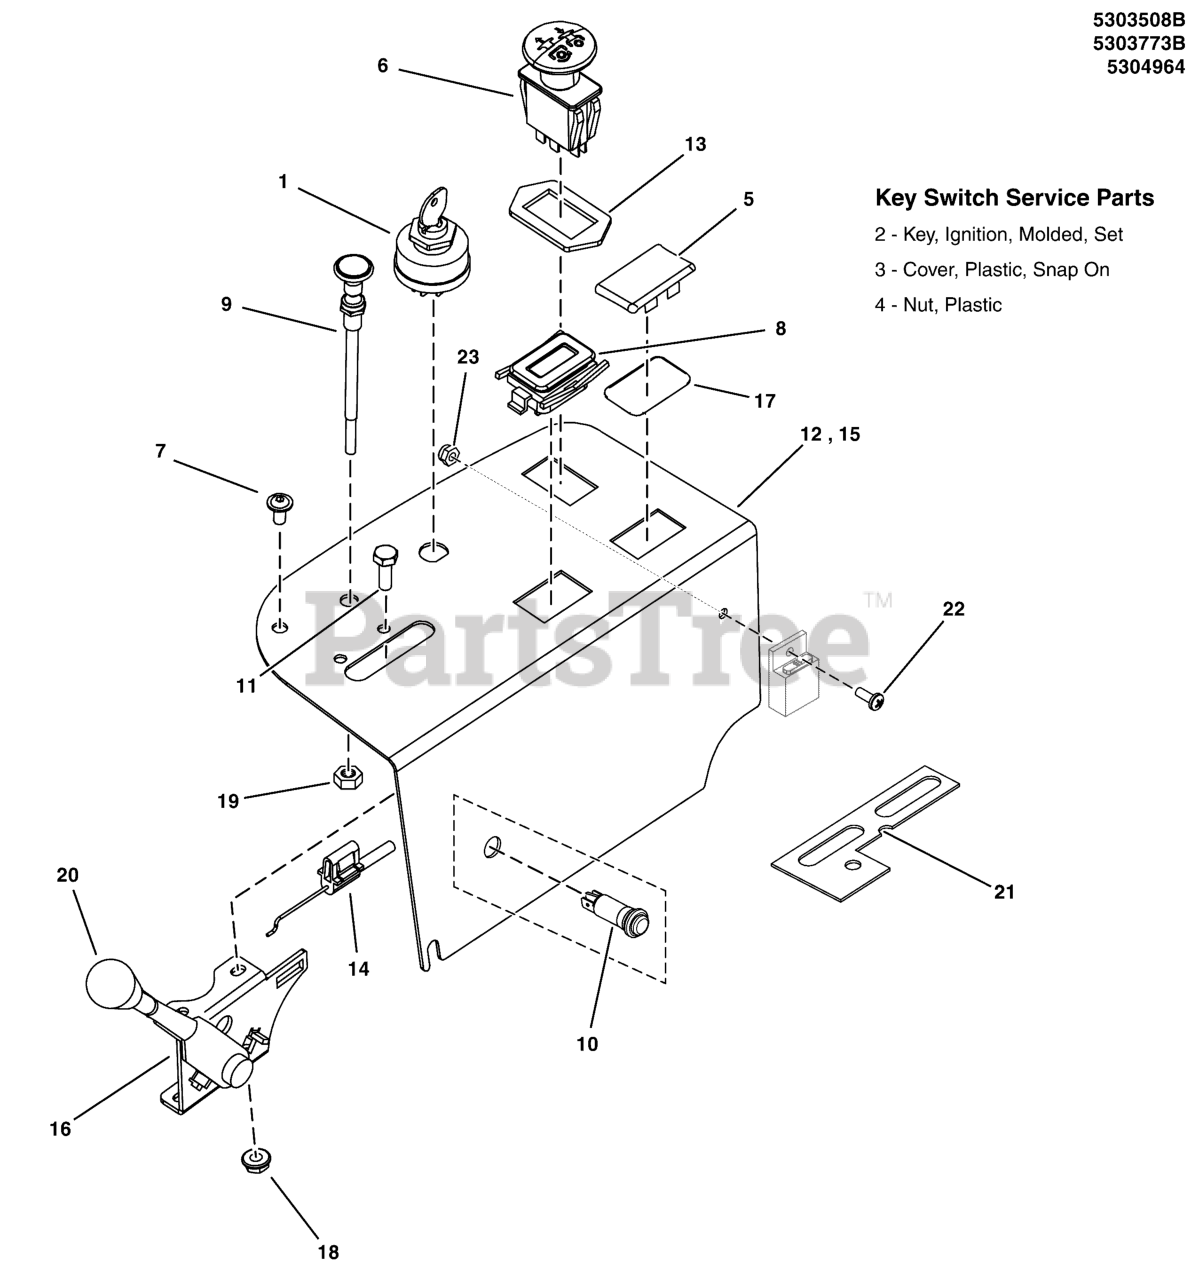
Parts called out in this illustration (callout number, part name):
1	SWITCH, IGNITION, 6 POST
2	KEY, IGNITION MOLDED SET
3	COVER, PLASTIC, SNAP ON
4	PLASTIC NUT
5	PLUG, .820X1.44 HOLE, BLACK PLASTIC
6	SWITCH-PTO PUSH
7	SCREW, ALLEN HEAD 1/4-20X.500 ZINC PHOS
8	HOUR METER, ASSEMBLE
9	CABLE, Choke Control, 47"
10	LIGHT, INDICATOR, PANEL, LED, RED
11	SCREW, #10-24 X 3/4" ROUND PHILLIPS
12	PANEL, Control - Black
13	RING, SWITCH RETAINER
14	CABLE, THROTTLE, 42"
15	PANEL, CONTROL, IS2100/3200 - BLK
16	LEVER, THROTTLE CONTROL, HEAVY-DUTY
17	O-RING, 7/8" ID X 1/16" W
18	NUT, Hex, Nylon Lock, #10-24
19	NUT, 3/8-24 HEX (SV)
20	THROTTLE CONTROL HANDLE/KNOB
22	SCREW, #10-24 X 1/2" ROUND PHILLIPS
23	NUT, Hex, Nylon Lock, #10-24
